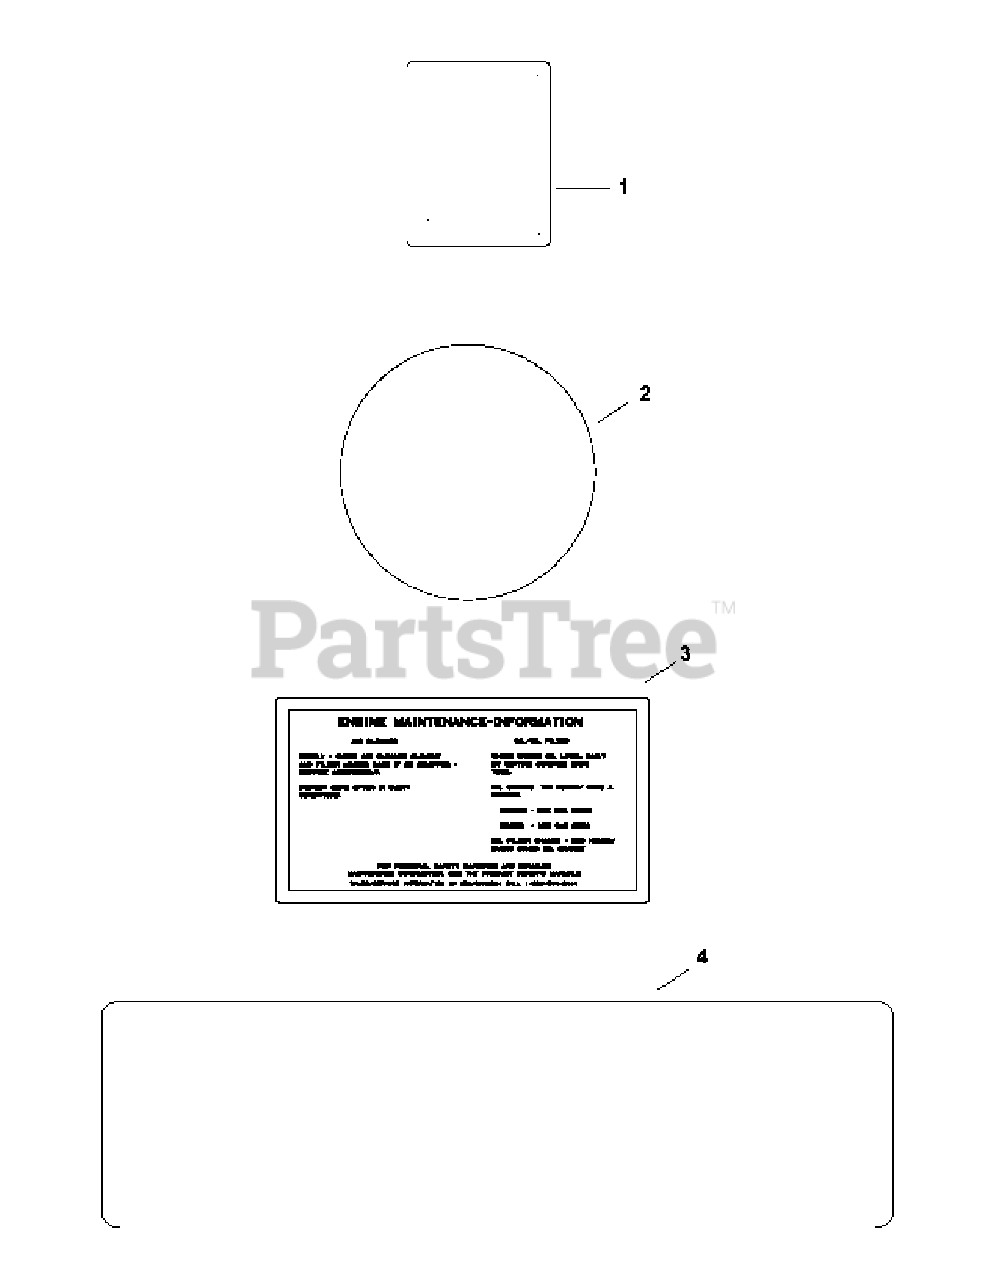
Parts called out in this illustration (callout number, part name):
1	Clear Laminate Decal
2	Grass Screen Decal
3	Air Cleaner Decal
